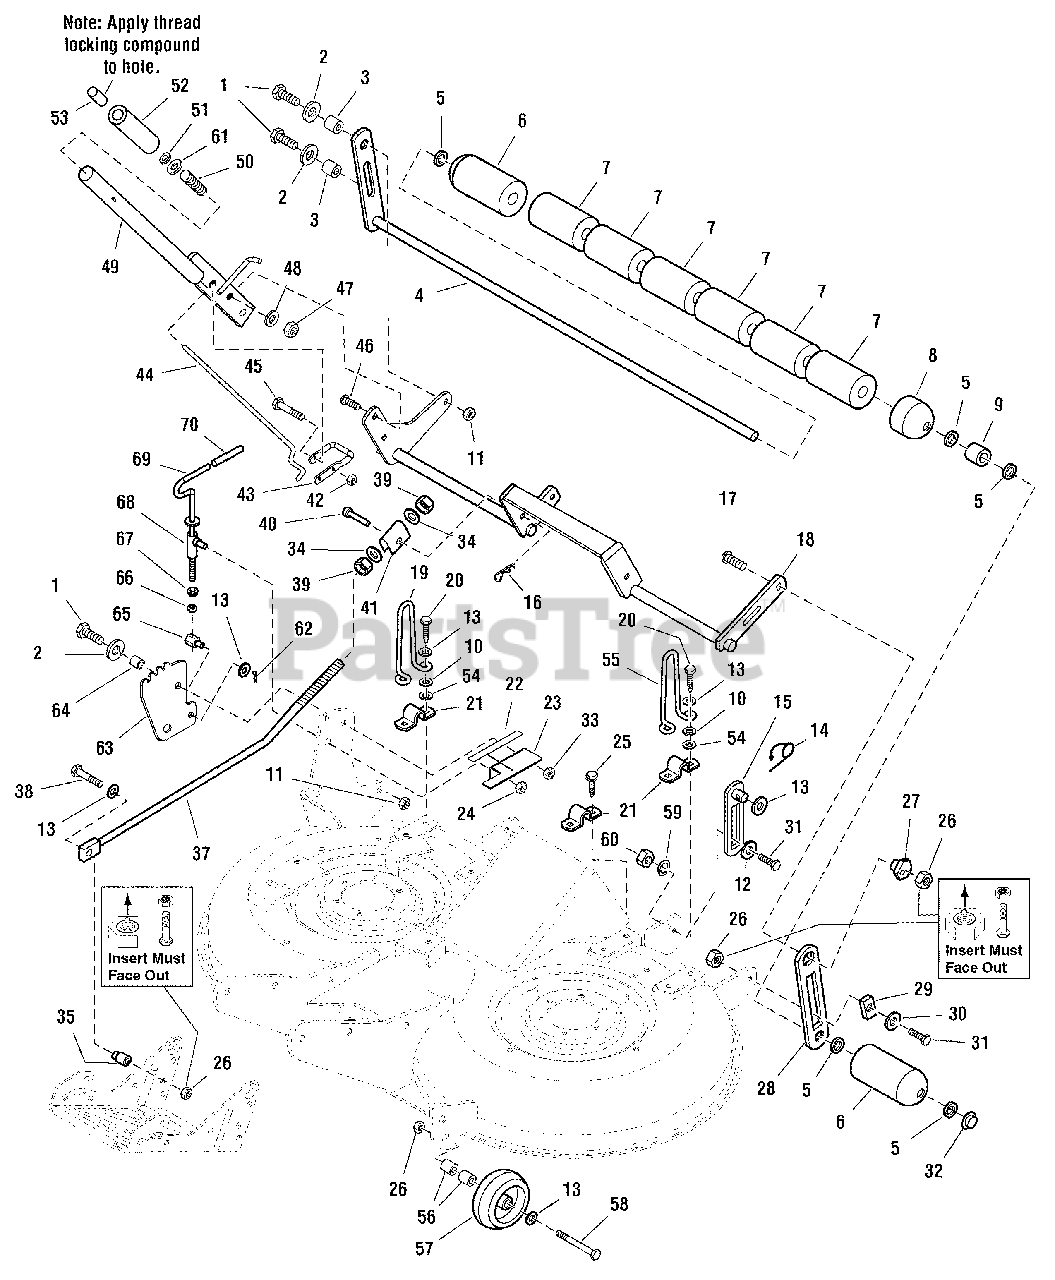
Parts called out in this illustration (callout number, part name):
1	CAPSCREW, Hex Head, 5/16-18 x 1-1/4
2	WASHER
3	SPACER
4	SHAFT & BAR ASSEMBLY
5	WASHER
6	ROLLER
7	ROLLER
8	ROLLER
9	SPACER
10	WASHER
11	NUT, Hex Flange Lock, 5/16-18
12	WASHER, 3/8
13	WASHER
14	RETAINER, Pin
15	LINK & PIN ASSEMBLY
16	PIN, Retaining
17	CARRIAGE BOLT, 3/8-16 x 1-1/2
18	SHAFT & ARM ASSEMBLY
19	STOP, Up
20	CAPSCREW, Hex Head Taptite, 5/16-18 x 1-1/4
21	STRAP
22	DECAL, Height of Cut
23	BRACKET, Height of Cut
24	NUT, Hex Lock ESNA Light, 5/16-18
25	CAPSCREW, Hex Head Taptite, 5/16-18 x 3/4
26	NUT, Spiral Flange Toplock, 3/8-16
27	NUT, Hex Adjusting
28	BAR
29	SLIDE
30	WASHER
31	SHOULDER BOLT, 3/8-16
32	NUT, Push
33	NUT, Hex Centerlock, 3/8-16
34	WASHER, 21/32 x 1 x 1/64
35	SPACER
37	ROD, Adjusting
38	CAPSCREW,Hex Head, 3/8-16 x 1-3/4, GR8
39	NUT, Hex, 5/8-11
40	PIN, Round Head Drilled, 3/8 x 2
41	TRUNNION
42	NUT, Hex Lock ESNA, 1/4-20
43	LATCH, "U"
44	ROD
45	CAPSCREW, Hex Head 1/4-20 x 2-1/4
46	BOLT, Carriage, Short Neck, 5/16-18 x 1
47	NUT, Hex, 5/16-18
49	HANDLE ASSEMBLY, Lift
50	SPRING, Compression
51	NUT, Push
52	GRIP, Black
53	BUTTON, Red
54	NUT, Push
55	UPSTOP
56	SPACER
57	WHEEL, Gauge
58	CAPSCREW, Hex Head, 3/8-16 x 3
59	LOCKWASHER, 3/3
60	NUT, Hex, 3/8-16
61	WASHER, 11/32 x 11/16 x 1/16
62	PIN, Cotter, 15/16 x 3/4
63	BRACKET, Adjusting
64	SPACER, 21/64 x 1/2 x 7/32
65	PIVOT, 3/4 Hex
66	NUT, Hex Jam, 3/8-16 NC-2B
67	NUT, Hex Flange, 3/8-16
68	GUIDE ASSEMBLY, Rod
69	ROD & WASHER ASSEMBLY, Adjustment Handle
70	GRIP, Black Vinyl
0160	FRAME
